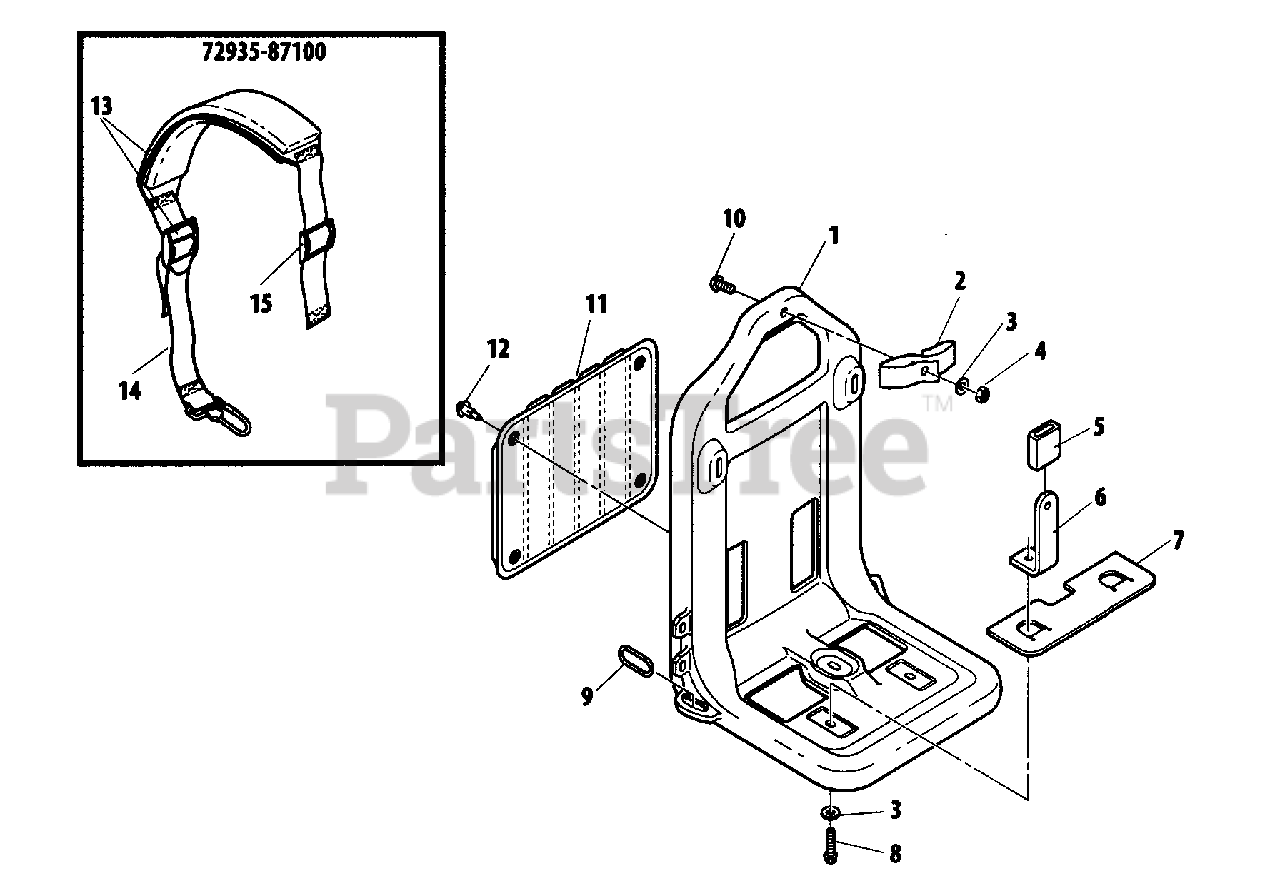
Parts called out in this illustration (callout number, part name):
1	FRAME
2	BAND
4	LOCKNUT - 6
5	CUSHION
6	BRACKET
7	CUSHION
8	SCREW - 6X20
9	HOOK, SPRING
10	SCREW - 6X30
11	PAD
12	CLIP
13	STRAP
14	STRAP
15	BUCKLE
72935-87100	BACKPACK STRAP KIT
